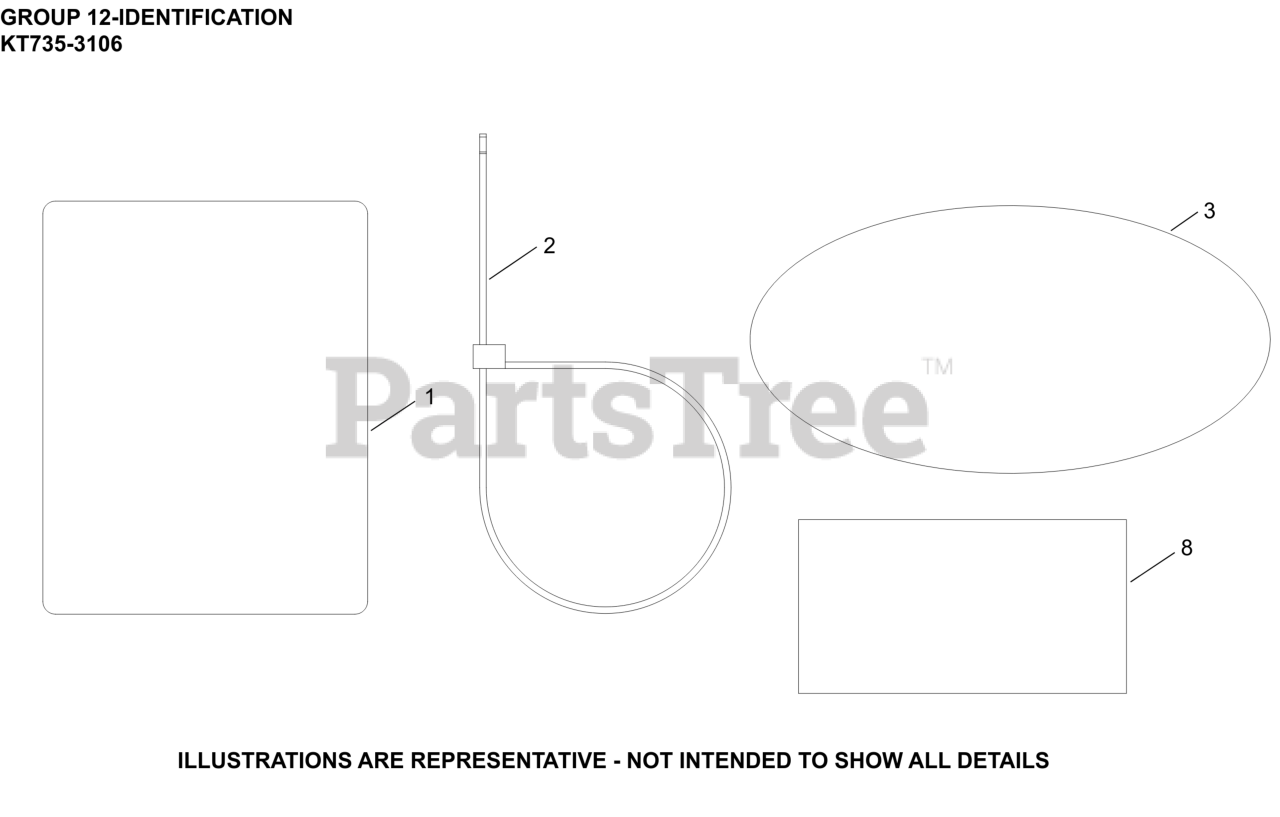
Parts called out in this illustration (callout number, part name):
1	LABEL, CLEAR LAMINATION
3	LABEL, 7000 SERIES KT735 (24 HP)
8	DECAL, USA
